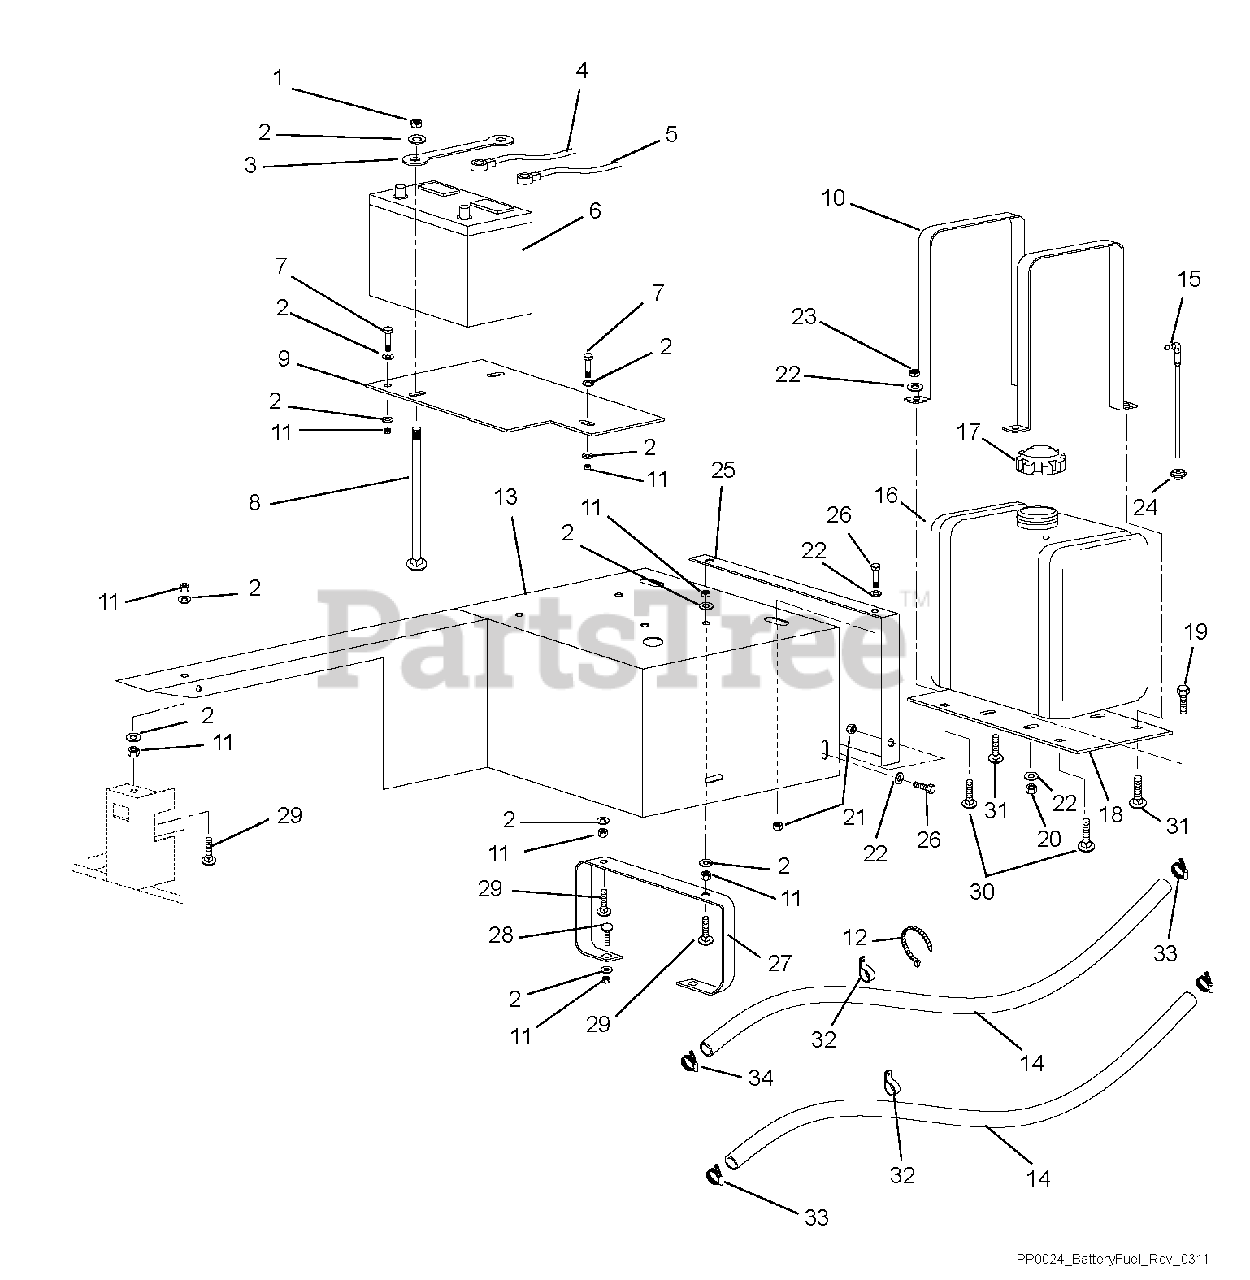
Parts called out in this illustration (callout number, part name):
1	Nut, Hex Jam Nylock .38-16
2	Washer, Flat .38
3	Plate, Battery Hold Down
4	Cable, Battery Positive
5	Cable, Battery Ground
7	Cap Screw, Hex Head .38-16 x 1.00
8	Bolt, Carriage .38-16 x 8
9	Plate, Battery Mounting
10	Strap, Fuel Tank Mounting
11	Nut, Lock .38-16 Crimp
12	Cable Tie .187 x 14.25
13	Weldment, Belt Guard
14	Hose, Fuel .25 I.D.
15	Assembly, Fuel Pickup
16	Tank, Six Gallon Fuel
17	Fuel Cap Vent-In Tethered
18	Mounting Plate, Fuel Tank
19	Cap Screw, Hex Head .312-18 x 1.00
20	Nut, Hex Serrated Flange .312-18
21	Nut, Locking Center .31-10
22	Washer, Flat .312
23	Nut, Hex Nyloc .312-18
24	Grommet, Viton
25	End Plate, Belt Guard
26	Cap Screw, Hex Head .312-18 x .75
27	Stand, Belt Guard
28	Bolt, Carriage .38-16 x 1.00
29	Bolt, Carriage .38-16 x 1.50
30	Bolt, Carriage .312-18 x 1
31	Bolt, Carriage .312-18 x 1.75
33	Gasline Clamp
34	Screw Clamp
